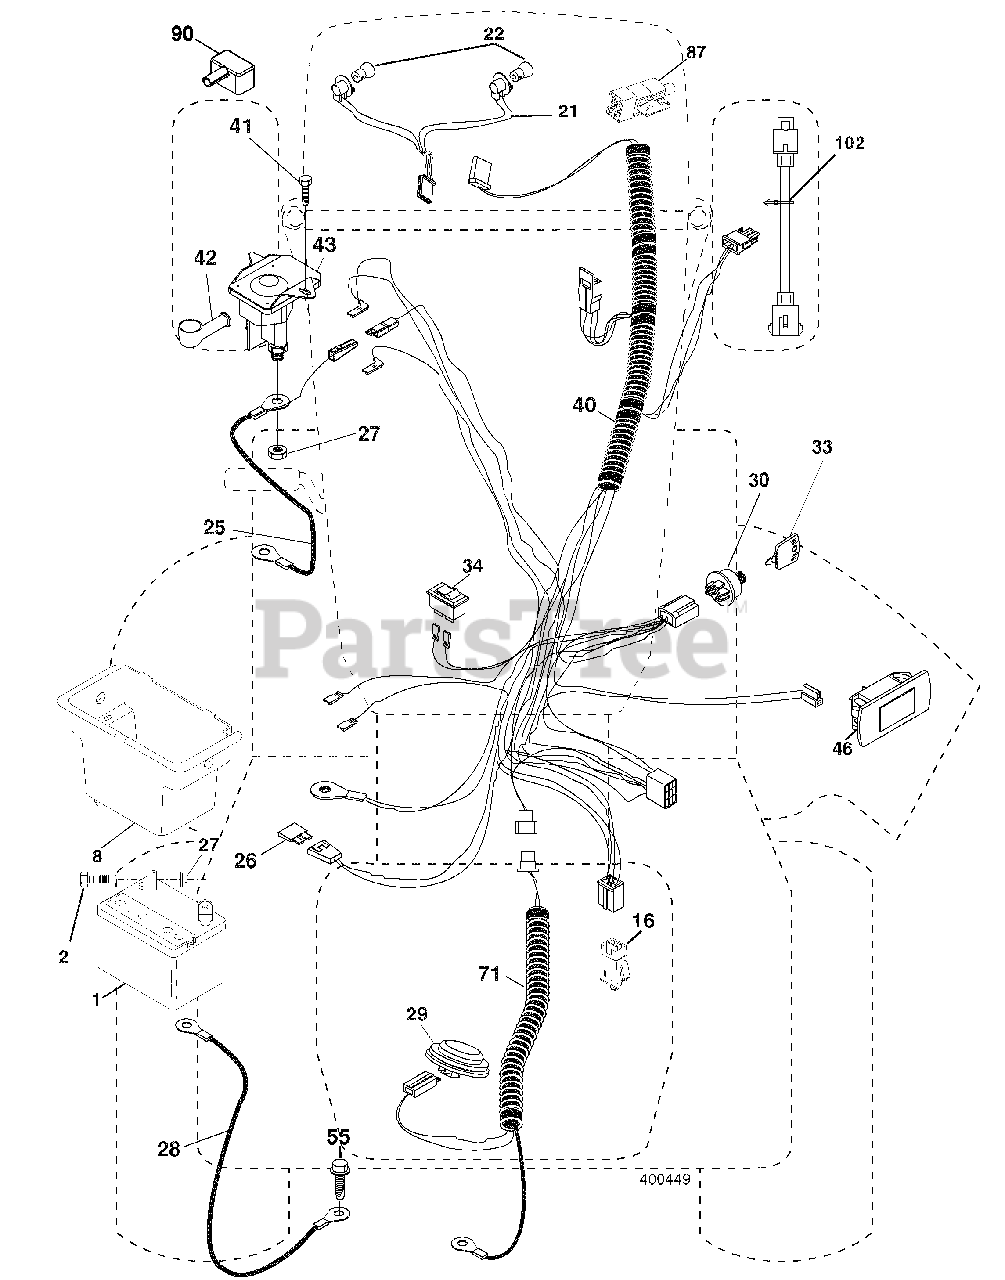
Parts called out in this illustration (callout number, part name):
1	Battery
2	Bolt Hex Head 1/4-20 x 3/4
8	Box Battery
16	Switch Interlock Push-In
21	Harness Socket Light W/4152J
22	Bulb Light
25	Cable Starter
27	Nut Keps Hex 1/4-20 unc
28	Cable, Ground
29	Switch, Seat
30	Switch, Ign
33	Key, Ignition
34	Switch Light / Reset
40	Harness Ign.
41	Screw Thd Cut 1/4-20 x 1/2
42	Cover, Terminal
43	Solenoid
46	Gauge Servicereminder Hrmtr
55	Screw Thdrol 5/16-18 x 3/4 TYTT
71	Harness Ign. Dash
87	Switch Interlock Clutch Cable
90	Cover Terminal
102	Harness Pigtail
